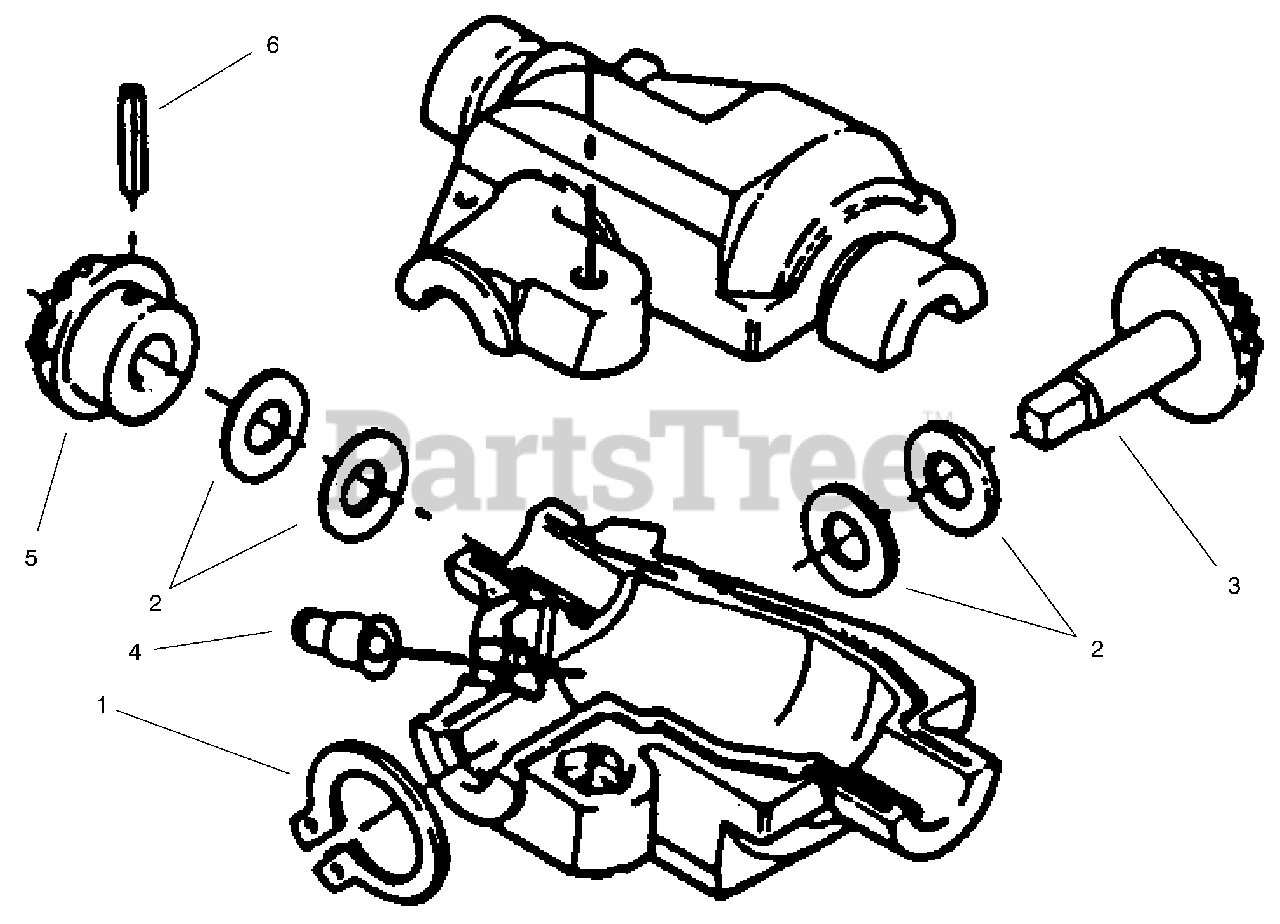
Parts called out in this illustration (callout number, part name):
1	Ring-Retaining
3	Gear-Driver
4	Zerk-Fitting
5	Gear-Driven
6	Spring Pin
